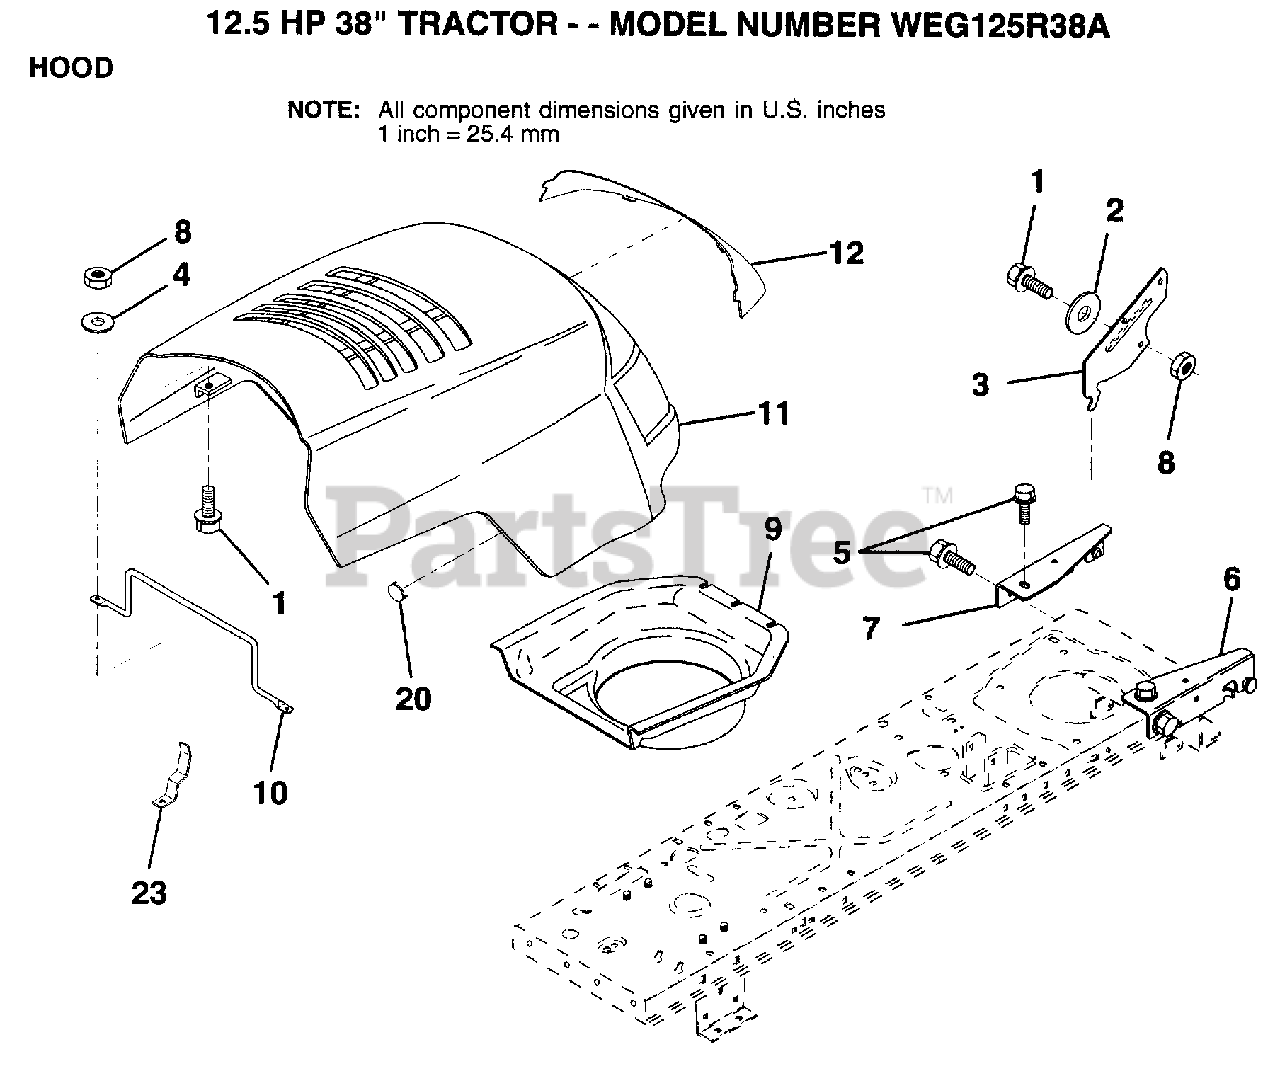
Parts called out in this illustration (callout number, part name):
1	BOLT LT
2	WASHER
3	BRACKET.PVT.HOOD
4	WASHER
5	SCREW
6	BRACKET ASM HD RH
7	BRACKET ASM HD LH
8	NUT
9	DUCT.INTAKE.AIR
10	ROD SUPT HOOD
12	LENS.PL.BAR.CLEAR
23	LATCH.HOOD.LR
